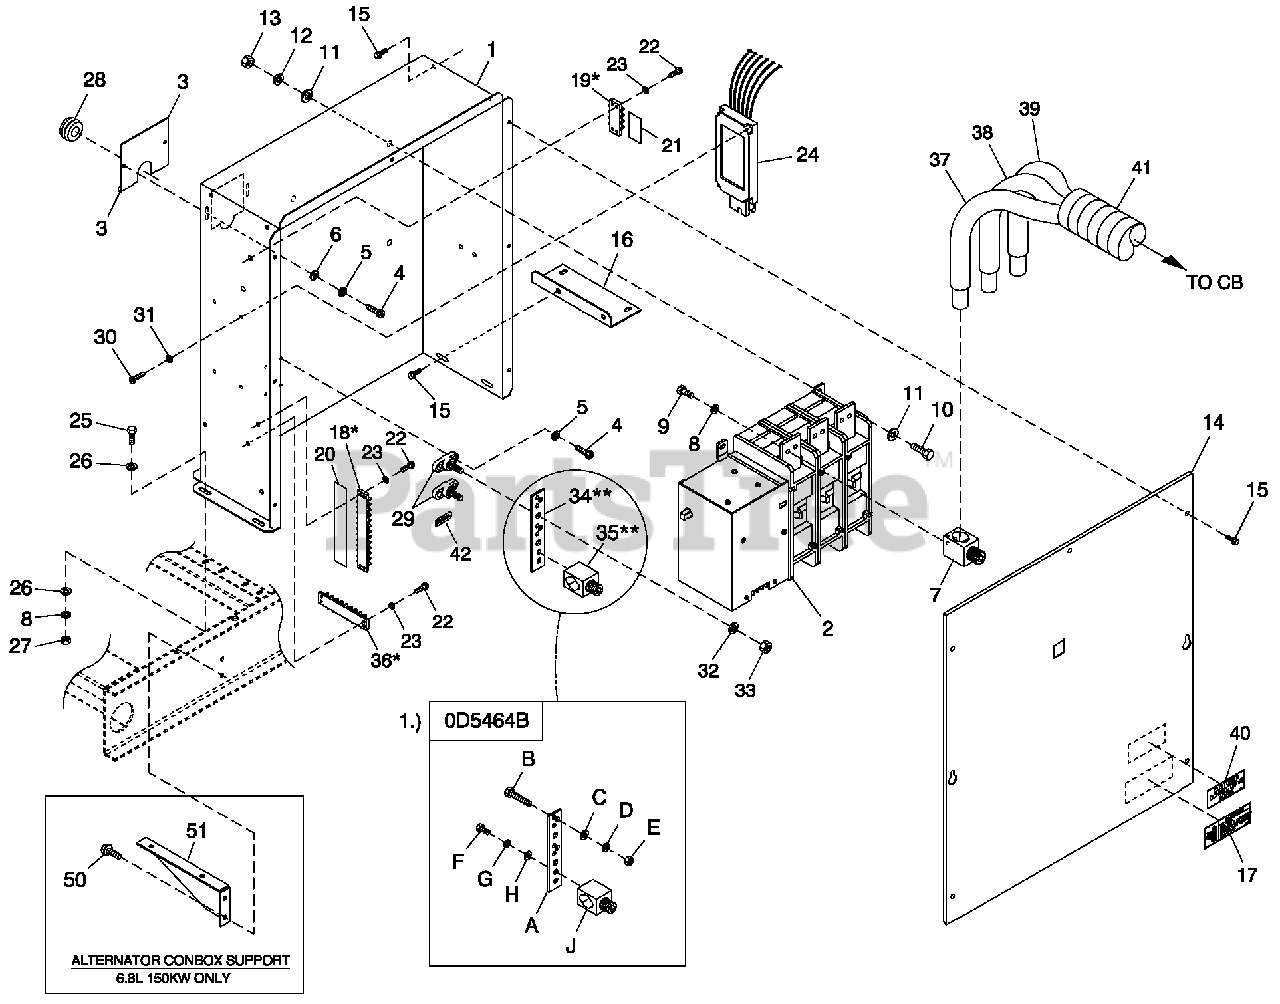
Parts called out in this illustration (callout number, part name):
1	CONBOX CONTACTOR 400A
2	CONTACTOR 400A 3P AC CL DC TR
3	PLATE WIRE SNGL GALV
4	SCREW PHTT M5-0.8 X 16 ZYC
5	WASHER LOCK M5
6	WASHER FLAT M5
7	LUG SLDLSS 600/250-1/0X1/4-28
8	WASHER LOCK M6-1/4
9	SCREW HHC 1/4-28 X 5/8 .625TH
10	SCREW HHC M8-1.25 X 20 G8.8
11	WASHER FLAT 5/16-M8 ZINC
12	WASHER LOCK M8-5/16
13	NUT HEX M8-1.25 G8 CLEAR ZINC
14	COVER CONTACTOR 400A
15	SCREW THF M6-1 X 16 N WA Z/JS
16	MOUNT CONTACTOR
17	DECAL DANGER HIGH VOLTAGE
18	BLOCK TERM 20A 12 X 6 X 1100V
19	BLOCK TERM 20A 6 X 3 X 1100V
20	DECAL CUSTOMER CONNECTION
21	DECAL CUSTOMER CONNECTION 120V UTILITY
22	SCREW PHTT #6-32 X 1/2 ZYC
23	WASHER LOCK #6
24	ASSY PCB 3PH VOLT DIV 480V L-L
25	SCREW HHC M6-1.0 X 20 G8.8
26	WASHER FLAT 1/4-M6 ZINC
27	NUT HEX M6 X 1.0 G8 YEL CHR
28	GROMMET 1.25 X .25 X .75
29	JUNCTION BLOCK 3/8-16
30	SCREW PPHM M4-0.7 X 10
31	WASHER LOCK #8-M4
32	WASHER LOCK 3/8
33	NUT HEX 3/8-16 STEEL
34	BUS BAR NEUTRAL BLOCK 390
35	LUG SLDLSS 600/250-1/0 X 1/4-28
36	BLOCK TERM 20A 8 X 6 X 1100V
37	ASSY WIRE #282 E1 3/0 76.0"
38	ASSY WIRE #283 E2 3/0 76.0"
39	ASSY WIRE #284 E3 3/0 74.0"
40	DECAL CUSTOMER CONNECT INSIDE
41	CONDUIT FLEX 2.0" ID
42	DECAL NEUTRAL
50	SCREW THF M6-1X16 N WA Z/JS
51	SUPPORT CONBOX TRANSFER SWITCH
A	BUS BAR NEUTRAL BLOCK 390
B	SCREW HHC M8-1.25 X 45 G8.8 FT
C	WASHER FLAT 5/16-M8 ZINC
D	WASHER LOCK M8-5/16
E	NUT HEX M8-1.25 G8 YEL CHR
F	WASHER FLAT 1/4-M6 ZINC
G	WASHER LOCK M6-1/4
H	SCREW HHC 1/4-28 X 5/8 .625TH
J	LUG SLDLSS 600/250-1/0 X 1/4-28
